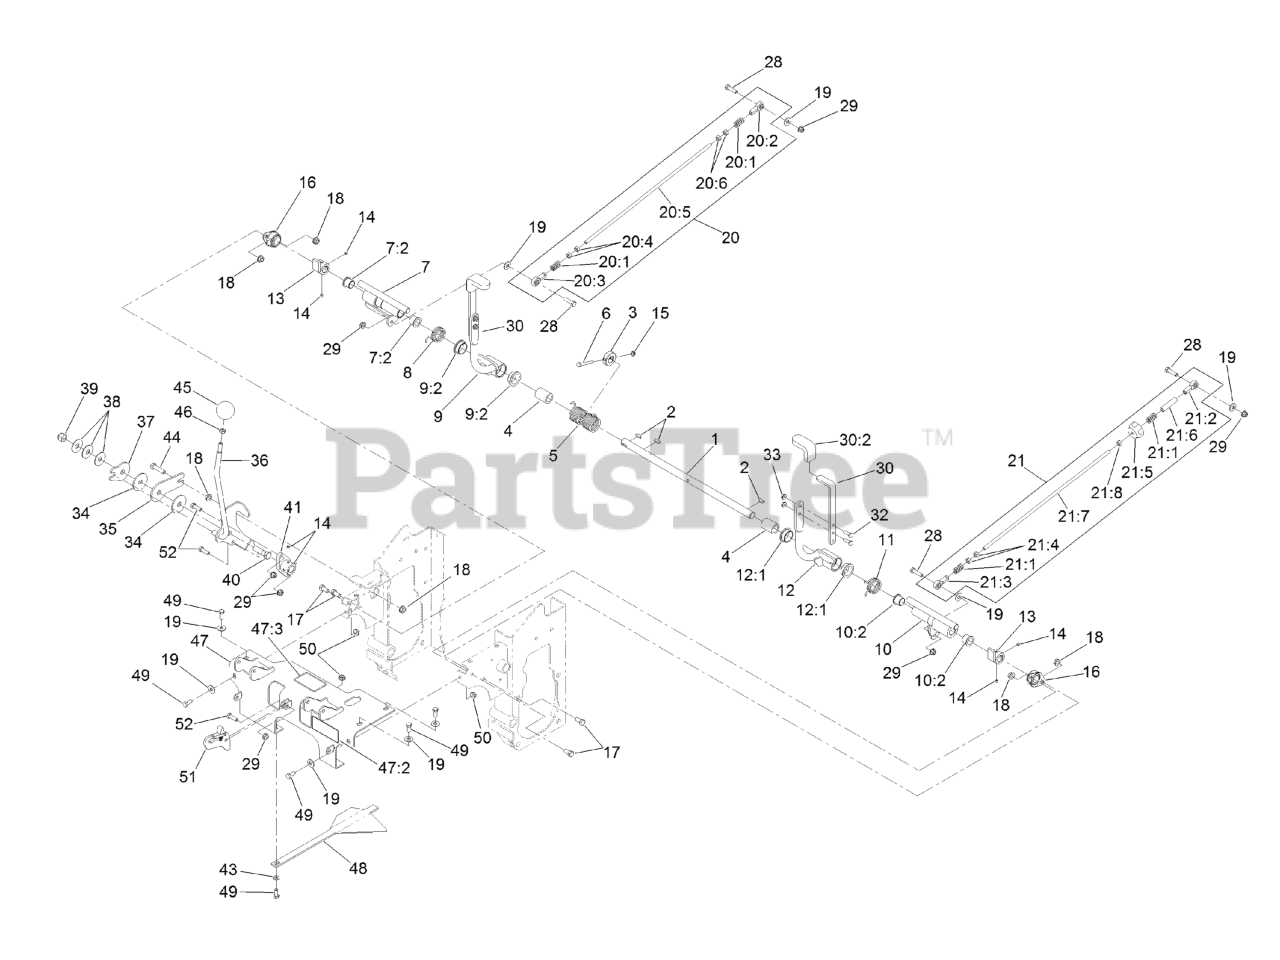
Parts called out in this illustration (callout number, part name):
1	SHAFT-CONTROL, SPEED
2	KEY-WOODRUFF
3	STOP-HUB, CENTER
4	BUSHING-PLASTIC
5	SPRING-TORSION, DOUBLE
6	SCREW-HH
7	RH CONTROL HUB ASM
7:2	BEARING-FLANGE, IGLIDE
8	SPRING-TORSION, RH
9	RH STEERING HANDLE ASM
9:2	BEARING-FLANGE, IGLIDE
10	LH CONTROL HUB ASM
10:2	BEARING-FLANGE, IGLIDE
11	SPRING-TORSION, LH
12	LH STEERING HANDLE ASM
12:1	BEARING-FLANGE, IGLIDE
13	HUB-SPEED CONTROL
14	SCREW-SET
15	NUT-LOCK, NI
16	BEARING-FLANGE, SIDE
17	SCREW-HH
18	NUT-HHF, WHIZ
19	WASHER-FLAT
20	RH PUMP LINKAGE ASM
20:1	SPRING-COMPRESSION
20:2	BALLJOINT-RH
20:3	BALLJOINT-LH
20:5	ROD-LINKAGE, STEERING
20:6	NUT-HEX
21	LH PUMP LINKAGE ASM
21:1	SPRING-COMPRESSION
21:2	BALLJOINT-RH
21:3	BALLJOINT-LH
21:5	KNOB-TRACKING
21:7	ROD-LINKAGE, STEERING
21:8	NUT-HEX
28	SCREW-HH
29	NUT-HF, NI
30	HANDLE ASM
30:2	GRIP-HANDLE, STEERING
32	SCREW-HH
34	DISC-FRICTION
35	PLATE-FRICTION, SPEED CON
36	LEVER-SPEED CONTROL
37	PLATE-FRICTION, SPEED CON
38	WASHER-DISC, SPRING
39	NUT-HEX
40	SCREW-HH
41	HUB-CONTROL, SPEED
43	WASHER-PLAIN
44	SCREW-HH
45	KNOB-BALL, SPEED CONTROL
46	NUT-JAM
47	CONSOLE ASM
48	GUIDE-PLENUM
49	SCREW-HH
52	SCREW-HH
